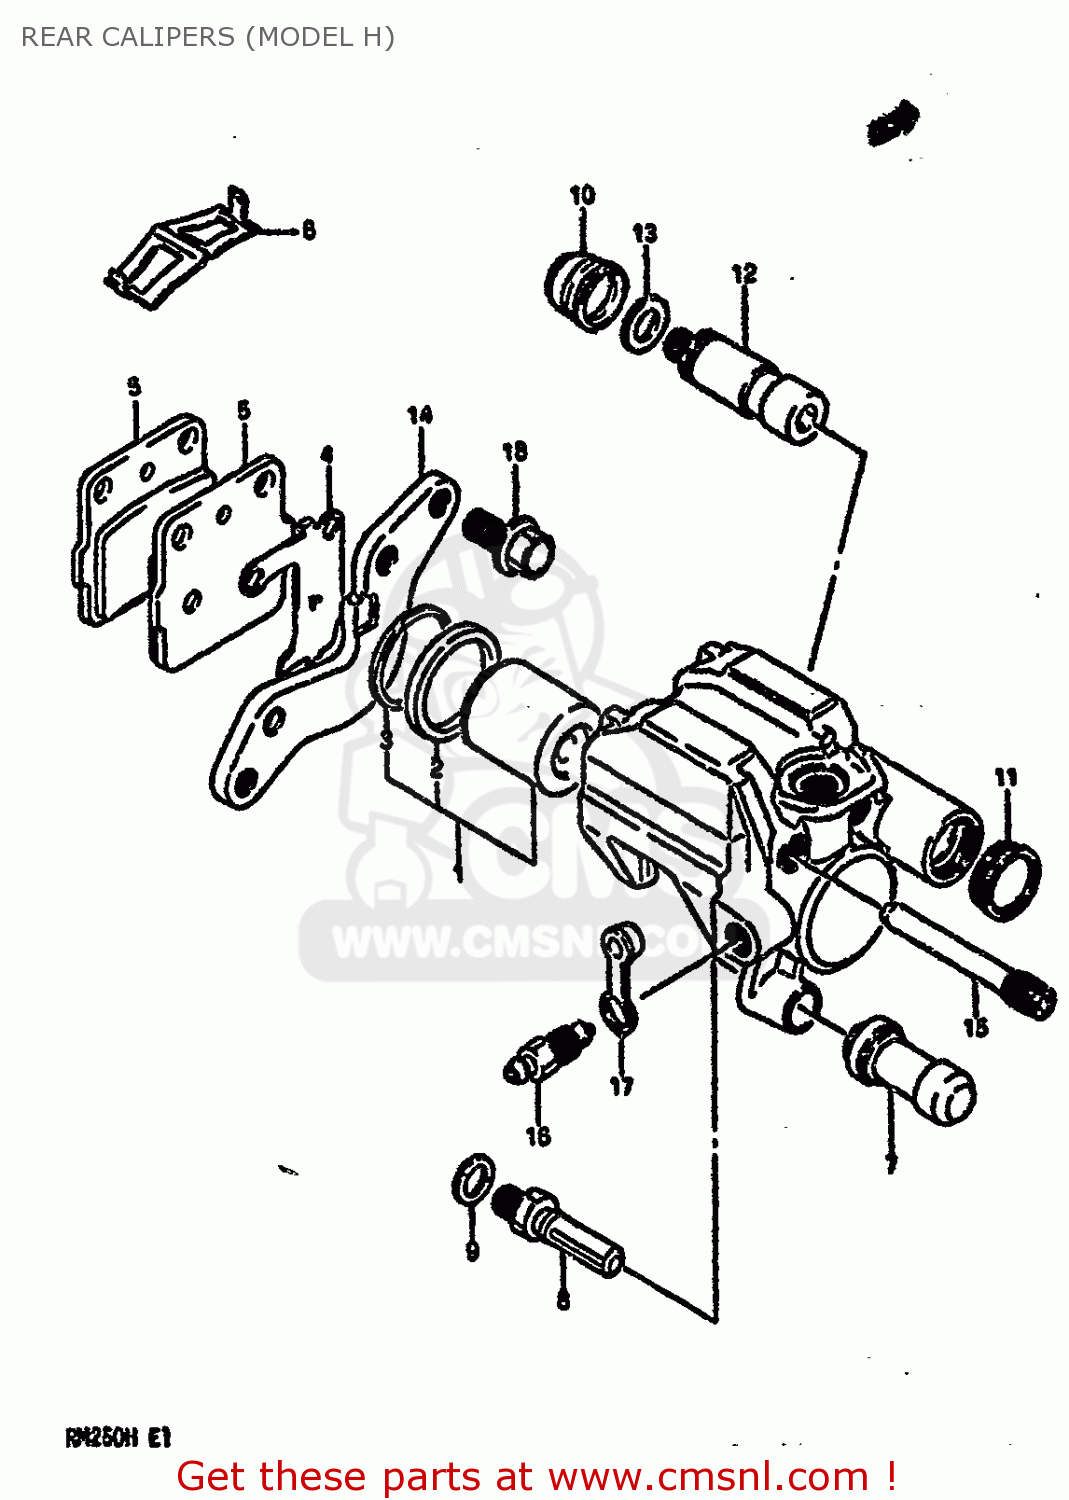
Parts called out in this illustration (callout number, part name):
1	PISTON SET
2	SEAL,PISTON
3	SEAL,DUST
4	SHIM
5	PAD
6	SPRING,PAD
7	BOOT
8	BOLT,PIN
9	WASHER,WAVE
10	BOOT,PIN
11	DUST SEAL
12	PIN,SLIDE
13	SPRING,FRICTION
14	BRACKET
15	PIN
16	BLEEDER
17	CAP,BLEEDER
18	BOLT(8X18)
